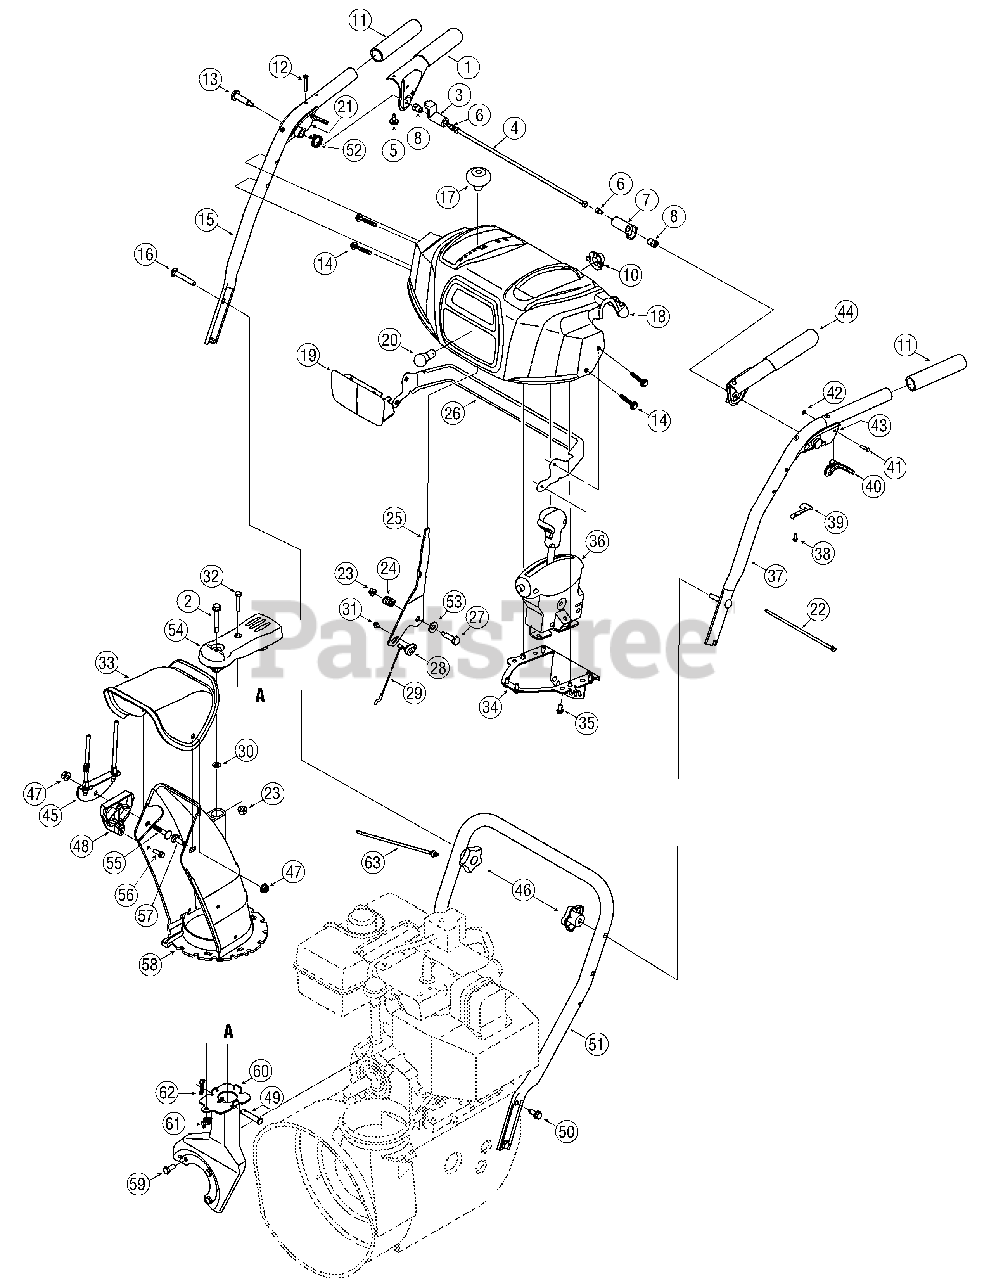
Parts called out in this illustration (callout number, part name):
1	Handle Engagement Assembly RH
2	Flange Shoulder Screw
3	Lock Plate
4	Pivot Rod
5	Rubber Bumper
6	Screw, 1/4-20 x.375
7	Clutch Lock Cam
8	Shoulder Nut, 1/4-20
10	Light Socket
11	Handle Grip
12	Screw, #10-24 x 0.375
13	Shoulder Screw, 1/4-20 x 1.345
14	Screw, 1/4-20 x 1.625
16	Carriage Screw, 5/16-18 x 2.25
17	Shift Knob
18	Handle Panel
20	Lamp
21	Handle Clutch Lock RH Assy
22	Cable Tie
23	Flange Lock Nut, 1/4-20
24	Compression Spring
27	Shoulder Screw
28	Cable Barrel Holder
29	Speed Selector Cable
30	Flat Washer, .25 x .630 x .0515
31	Screw, #10-16 x .500
32	Hex Screw, 1/4-20 x 1.50
33	Upper Chute
35	Hi-Lo Screw, 1/4-15 x 0.5
36	4 Way Chute Control Assembly Service Kit
38	Screw, #8-16 x 0.50
39	Clutch Lock Spring
40	Steering Control
41	Pin, 3/16
42	E Ring
43	Handle Clutch Lock LH Assy
44	Handle Engagement Assembly LH
46	Star Knob
47	Flange Lock Nut, 5/16-18
48	Chute Tilt Cable Guide
49	Clevis Pin
50	AB Screw, 5/16-18 x 0.75
52	Torsion Spring
53	Flat Washer
54	Joystick Pulley Cover
55	Carriage Bolt, 5/16-18 x 1.50
56	Hi-Lo Screw, 1/4-15 x .75
57	Carriage Bolt, 5/16-18 x 1.0
58	Lower Chute
59	Hex Screw, 5/16-24 x .750
60	Support Bracket
61	Wing Nut, 1/4-20
62	Bow Tie Cotter Pin
63	Cable Tie
